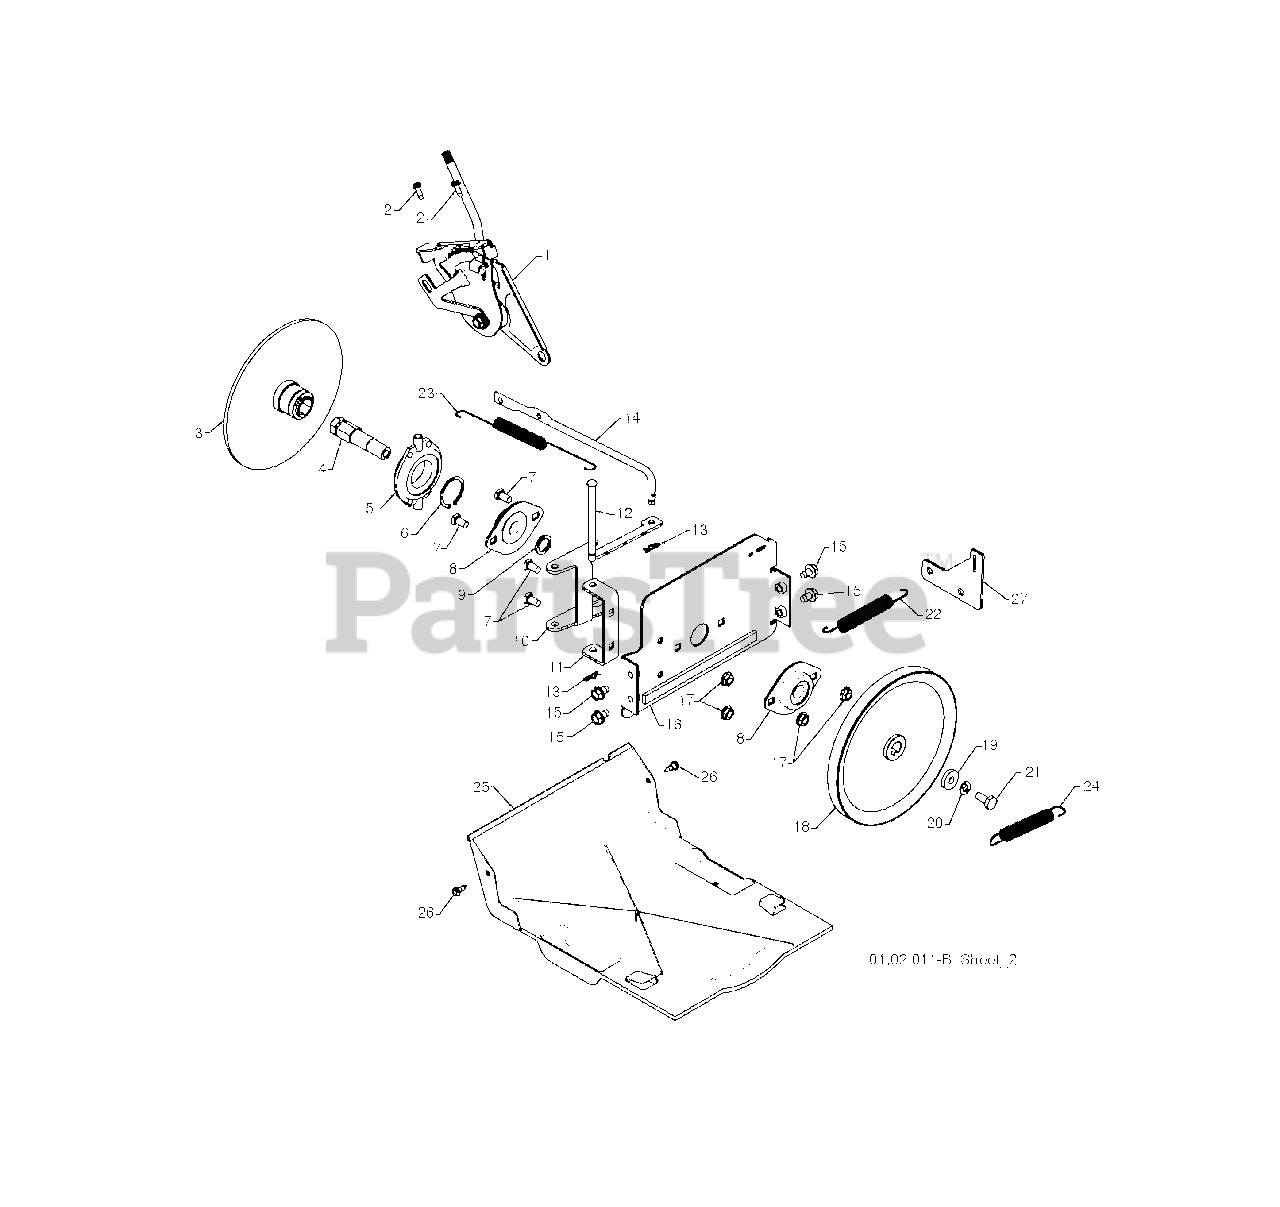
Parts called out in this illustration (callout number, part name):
1	HEAD ASSY SPEED
2	SCREW #10-24 X 5/8
3	DRIVE PLATE WELDMENT
4	SHAFT.HEX.SHORT
5	TRUNNION BEARING ASSY
6	RETAINING RING
7	BOLT
8	BEARING FLANGE
9	SPACER, BEARING
10	LEVER.SHIFTER.PLATE.BLACK
11	BRACKET.SHIFTER.SUPPORT.BLACK
12	PIN, PIVOT LEVER
13	RETAINER CLIP PM
14	ROD.CLUTCH.YELLOW.ZINC(VT)
15	SCREW LT
16	PLATE.DRIVE.MOUNT.BLACK
17	NUT.FLANGE.5/16
18	PULLEY.TRACTION.7.75
20	LOCKWASHER
22	SPRING.TRACTION.IDLER
23	SPRING.RETURN
24	SPRING, BRAKE
25	PAN.BOTTOM.PLASTIC
26	SCREW, HEX HEAD, TAPPING
27	BRACKET.TRACTION.SPRIN
